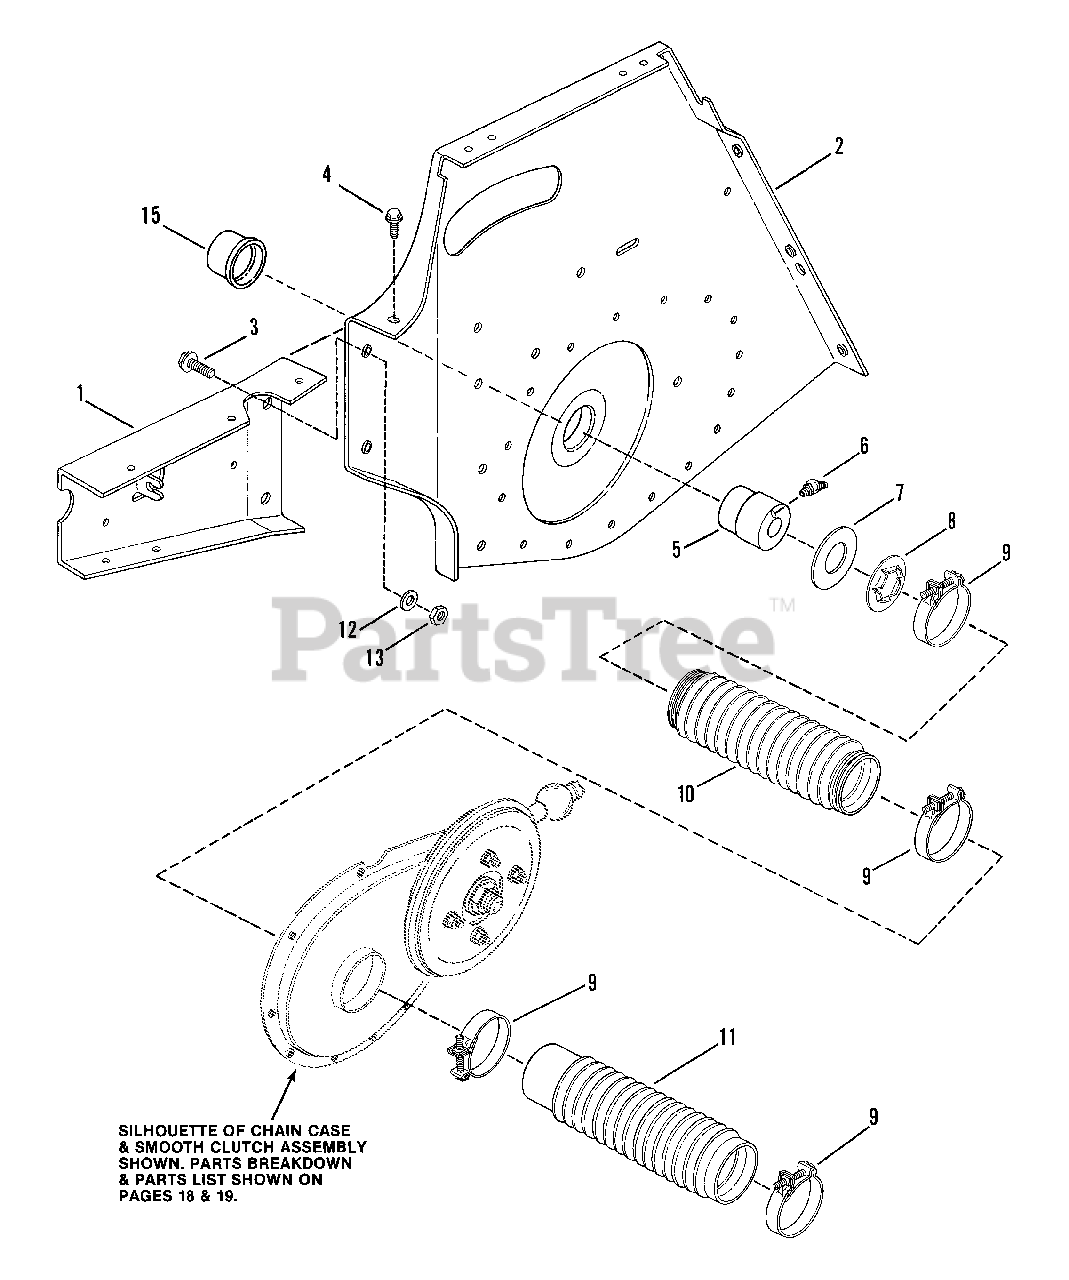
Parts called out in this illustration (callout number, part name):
1	EXTENSION, Transmission Support, R.H.
2	TRANSMISSION SUPPORT, R.H.
3	BOLT, 3/8-16x1" Hex Flange Lock
4	SCREW, 5/16-18x5/8" Self-Tapping
5	BEARING ASSM'Y., Axle
6	FITTING, Lube
7	WASHER, Thrust
8	WASHER, Thrust, Hex Drive Tube
9	CLAMP, Boot
10	BOOT, Oil Seal
11	BOOT, Oil Seal
12	WASHER, 3/8 SAE
13	NUT, 3/8-16 Center Lock
15	CAP, Seal L.H. 3/4"
